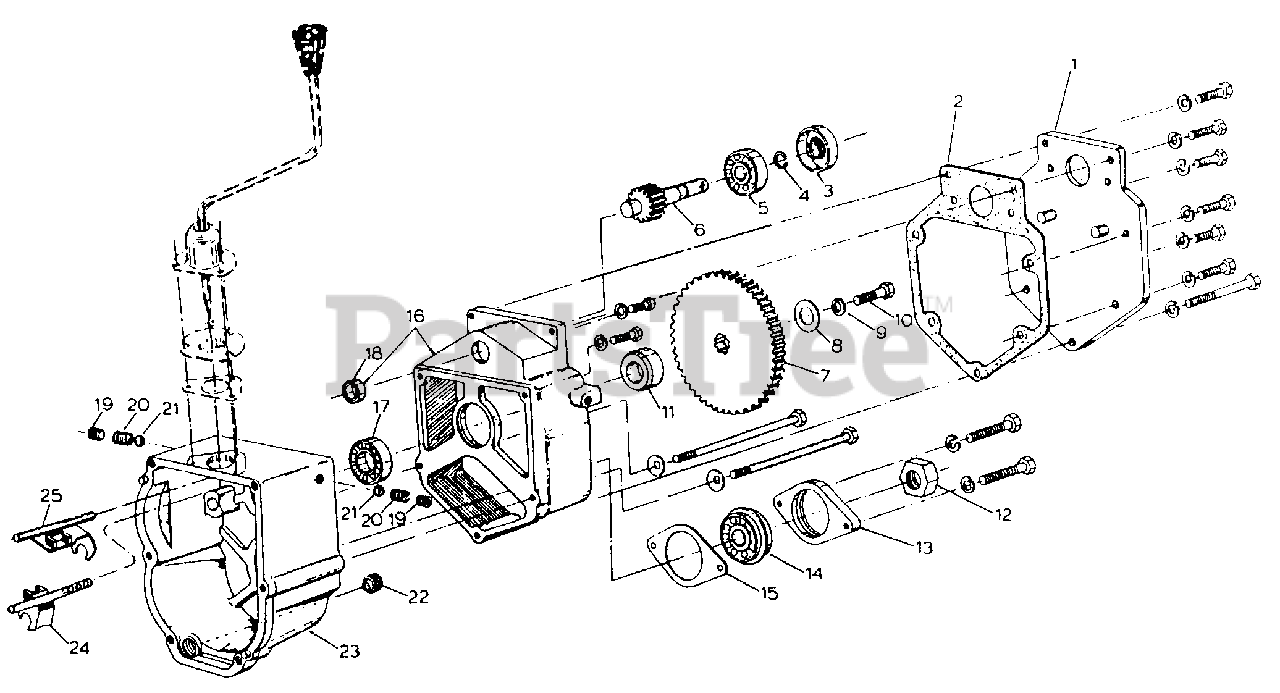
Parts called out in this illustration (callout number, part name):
1	Plate, Housing Cover
2	Gasket, Cover Plate
3	Seal, Drive Shaft Oil
4	Ring, Drive Shaft Bearing Retainer
5	Bearing, Drive Shaft Front Ball
6	Shaft, Drive
7	Gear, Drive -84T
8	Washer, 469 X 1.250 X .164 Pln
9	Washer, 7/16 Pln Lock
10	Bolt, 7/16 X 1.0 Pln Type 5
11	Spacer, Gear
12	Nut, 3/4-NF Pln Jam Type 5
13	Retainer, Countershaft Bearing
14	Bearing, Front Ball
15	Shim, Bearing Retainer, .004
16	Housing Assy, Reduction Drive w/Bearing
17	Bearing Assy, Main Shaft Front Ball
18	Bearing Assy, Drive Shaft Rear Needle
19	Screw, 1/2 X 7/16 Hdls Set
20	Spring, Gear Shift Poppet
21	Ball, 3/8 Grade 200 Metal Gear Shift Poppet
22	Plug, 1/2-14 Pln H/Hd Pipe Reduction Drive Hsg Drain
23	Housing, Front Gear
24	Fork, First and Reverse Speed Shift
25	Fork, Second and Third Speed Shift
